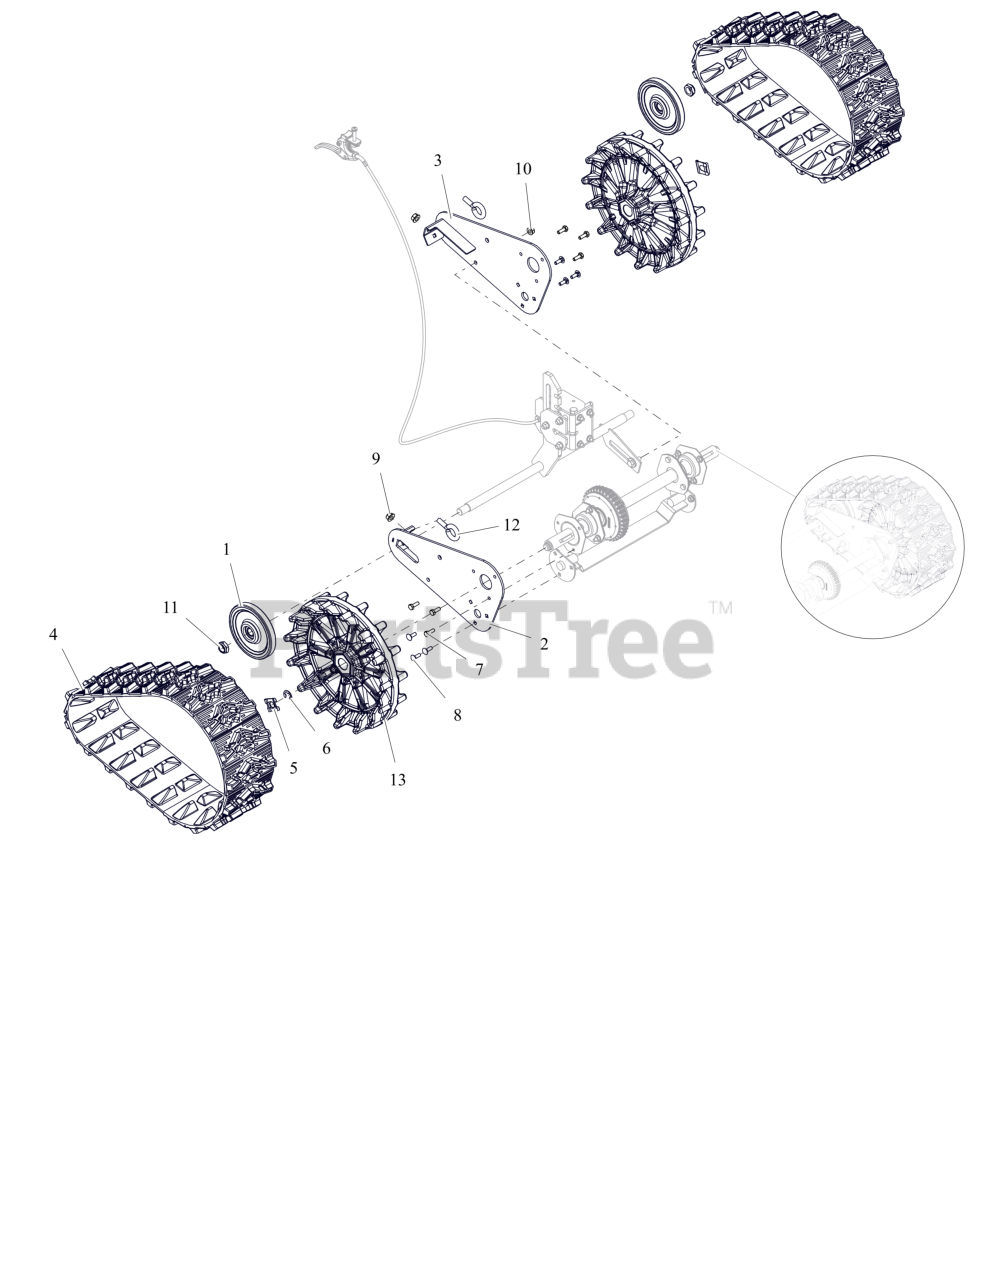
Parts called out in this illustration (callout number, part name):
1	WHEEL, BOGIE - SINGLE BEARING
2	PLATE- LH-COMP BWT WELDMT
3	PLATE- LH-COMP BWT WELDMT
4	TRACK, RUBBER
5	CLIP, SNAP .625 DIA
6	RG-RTNG-EXT .625X.042
7	BLT, HEX .25-20X.75 G5 ZCC
8	BLT, RHSN .25-20X.750 G5 ZCC
9	NUT-LK-CTR-FLG .375-16 GF ZCC
10	NUT-LK-TOP-FLG .312-18 GF ZCC
11	NUT, NYL LK .625-18 ZCC
12	BLT-EYE .375-16X.880 YWZC
13	WHEEL- COMPACT PLASTIC DRIVE
